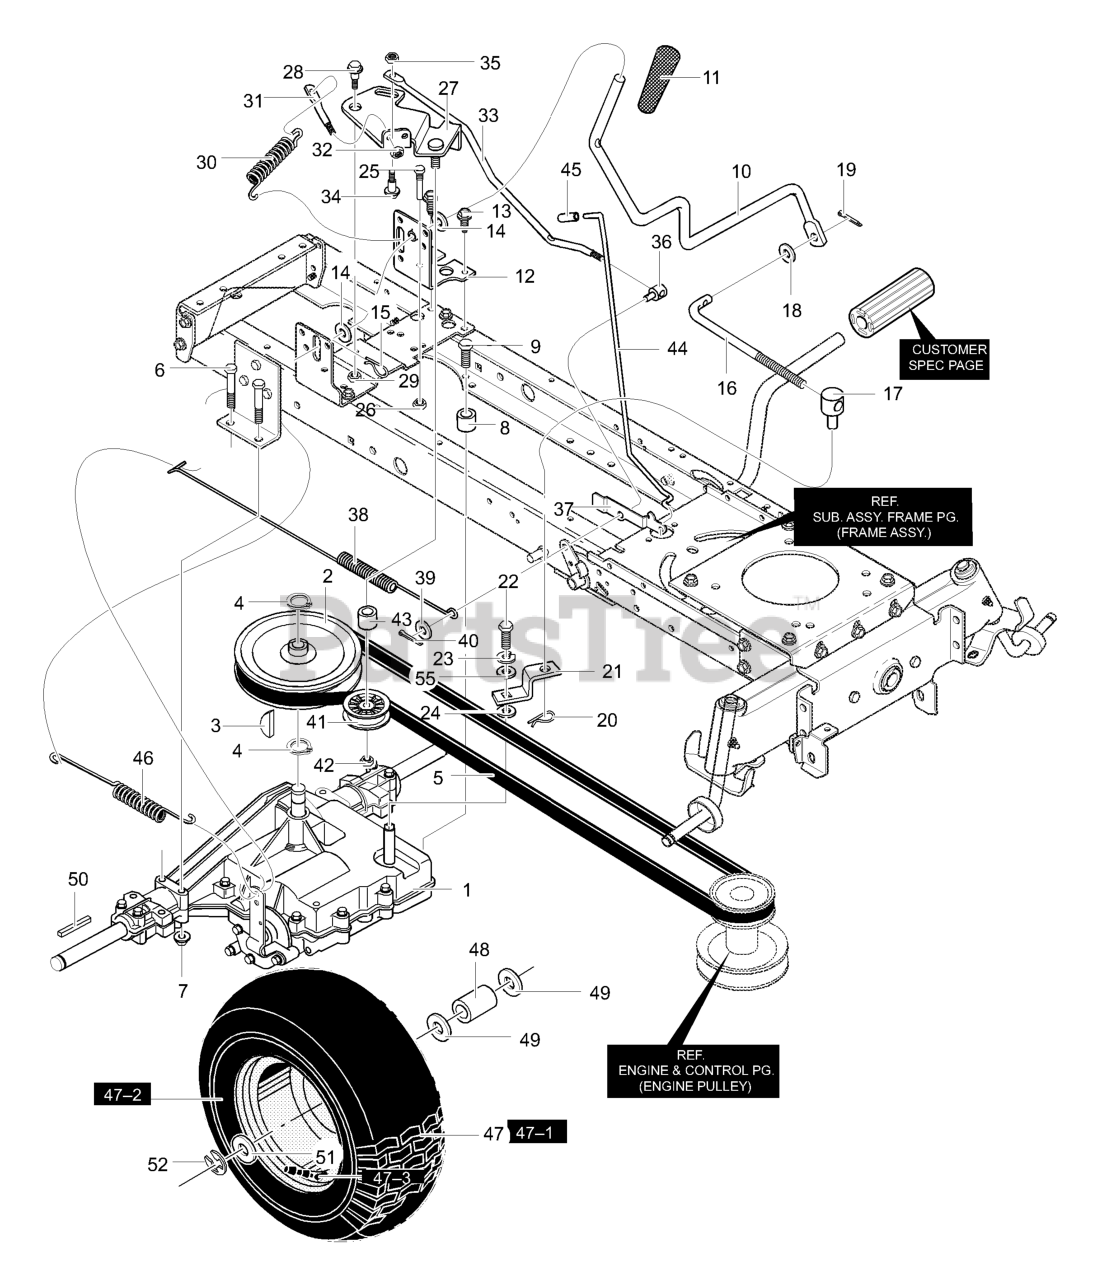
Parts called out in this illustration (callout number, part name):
1	Transaxle, MST205 **
2	Pulley, 8.81 Dia
3	Woodruff Key #9
4	Ring-Snap
5	Belt, V
6	Screw, 5/16-18 x 2.50
7	Nut, 5/16-18 Wdfllk
8	Spacer, Transaxle
9	Screw, 5/16-18 x 2.00
10	Shifter Lever
11	Grip
12	Bracket, Shift Pivot
13	Screw, 5/16-18 x 0.75
14	Flat washer
15	Hair Pin
16	Link, Shift
17	Adjusting Nut
18	Flat washer
19	Cotter Pin
20	Hair Pin
21	Yoke-Shift
22	Screw, 1/4-28x.75
23	Washer
24	Washer, .38 SQ
25	Screw Guide
26	Nut, 5/16-18 Hexwdfllk
27	ARM, Idler
28	Bolt, HHSH 3/8-16
29	Nut, 3/8-16 Hwdfllk Mack
30	Spring, Extension
31	Stud-Spring
32	Nut, 5/16-18 Hexwdfllk Whiz
33	Rod, Clutch Switch
34	Bolt, HHSH 1/4-20x.5
35	Nut, 1/4-20 Wdfllk
36	Nut, Adjusting
37	Latch, Park Brake
38	Extension Spring
39	Flat washer
40	Cotter Pin
41	Idler Pulley
42	Nut, 3/8-16 Hwdfllk Mack
43	Spacer 1/2 to 17MM
44	Park Brake Rod
46	Spring, Tension
47	Tire & Rim
47-1	Valve Stem
48	Spacer .87x1.78
49	Flat washer
50	Square Key
51	Flat washer
55	Flat washer
